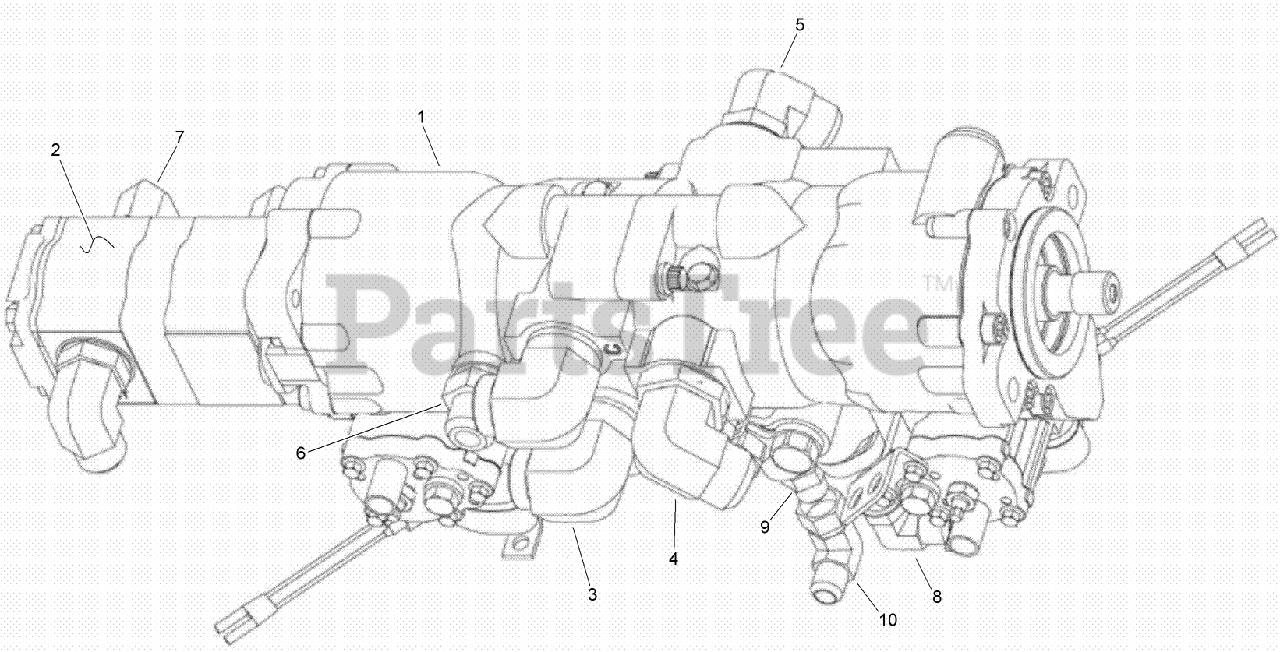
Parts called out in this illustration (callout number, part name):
1	TANDEM PUMP ASM
2	HYD GEAR PUMP ASM
3	ELBOW-90 Adj 1.0 ORFS-ORB
4	ELBOW-90
5	ELBOW-90 DEG
6	FITTING-STRAIGHT
7	ELBOW-90 Adj 37FL 3/4 Tube
8	ELBOW-90 Adj 37FL 5/8 Tube
9	CONNECTOR-Str Thd 5/8, 37FL-ORB 5/8
10	ELBOW-90 Swivel 37FL 5/8 Tube
